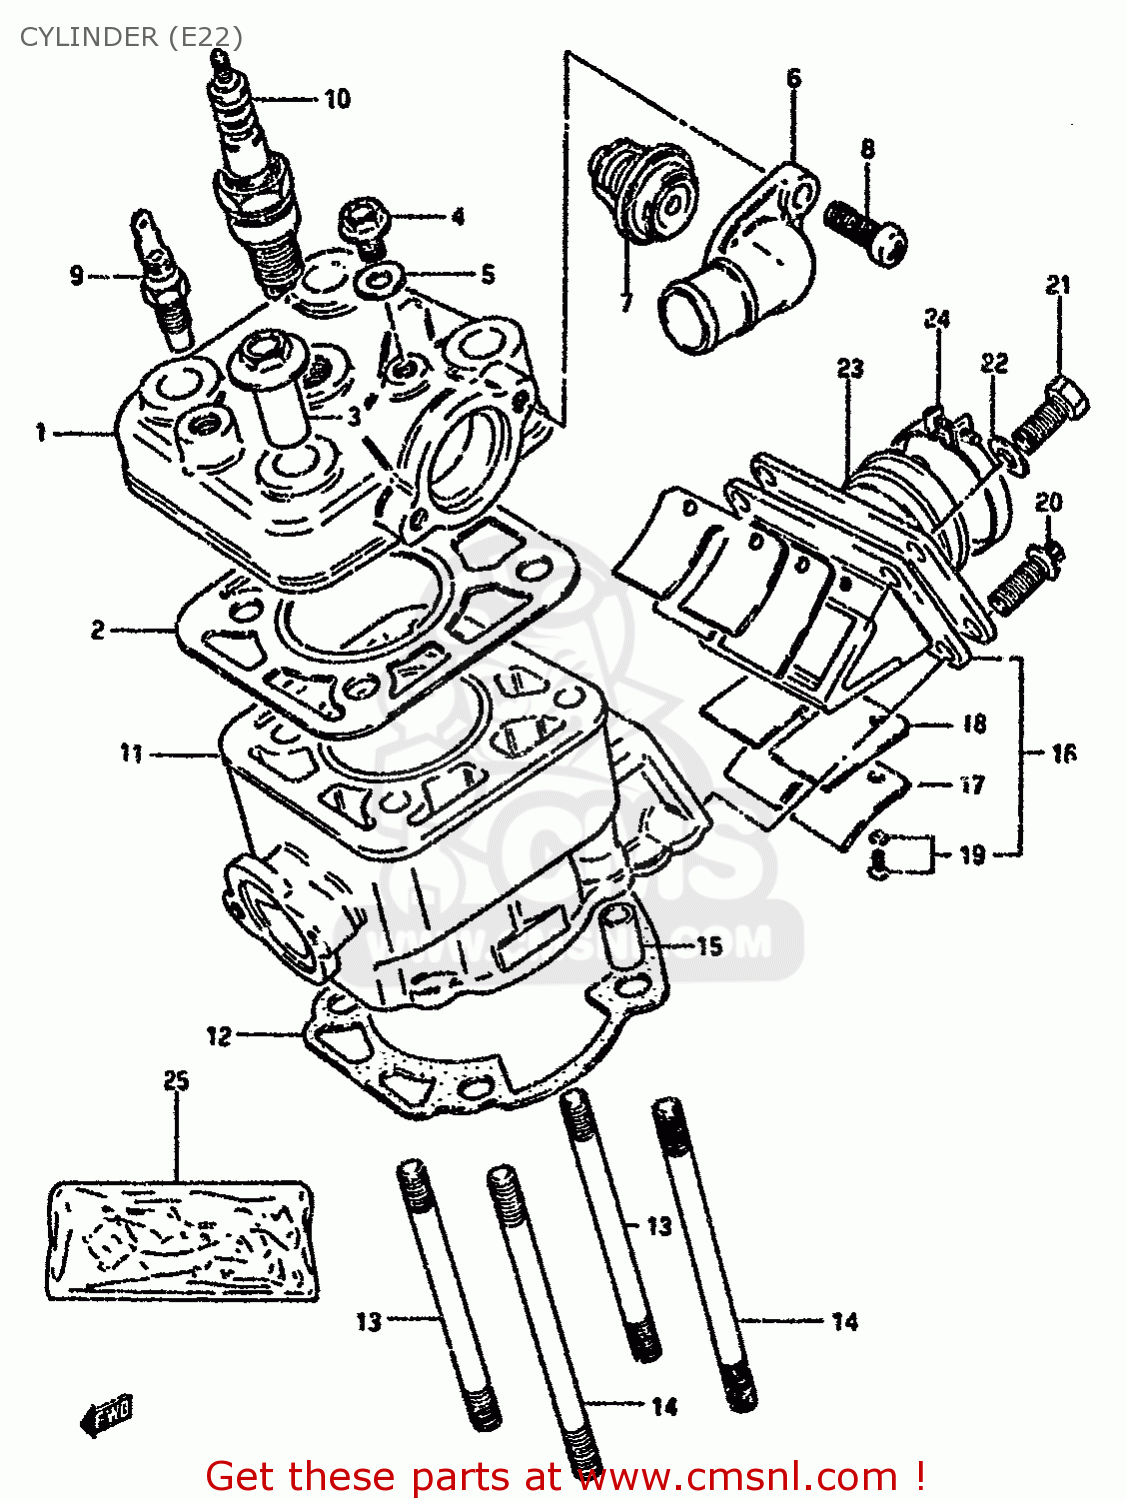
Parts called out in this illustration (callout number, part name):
1	HEAD,CYLINDER
2	GASKET,CYLINDER HEAD (NAS)
3	NUT
4	UNION
5	GASKET(6.2X11X1).2 (NAS)
6	COVER,THERMOSTAT
7	THERMOSTAT,WATER
8	SCREW
9	GAUGE ASSY,WATER TEMP
10	SPARK PLUG W22EP
11	CYLINDER
12	GASKET,CYLINDER (NAS)
13	STUD BOLT (L:100)
14	STUD BOLT (L:110)
15	PIN
16	VALVE ASSY,REED
17	STOPPER,REED VALVE
18	VALVE,REED
19	SCREW,REED VALVE
20	SCREW(6X20)
21	BOLT
22	WASHER
23	PIPE,INTAKE
24	CLAMP
25	GASKET SET
